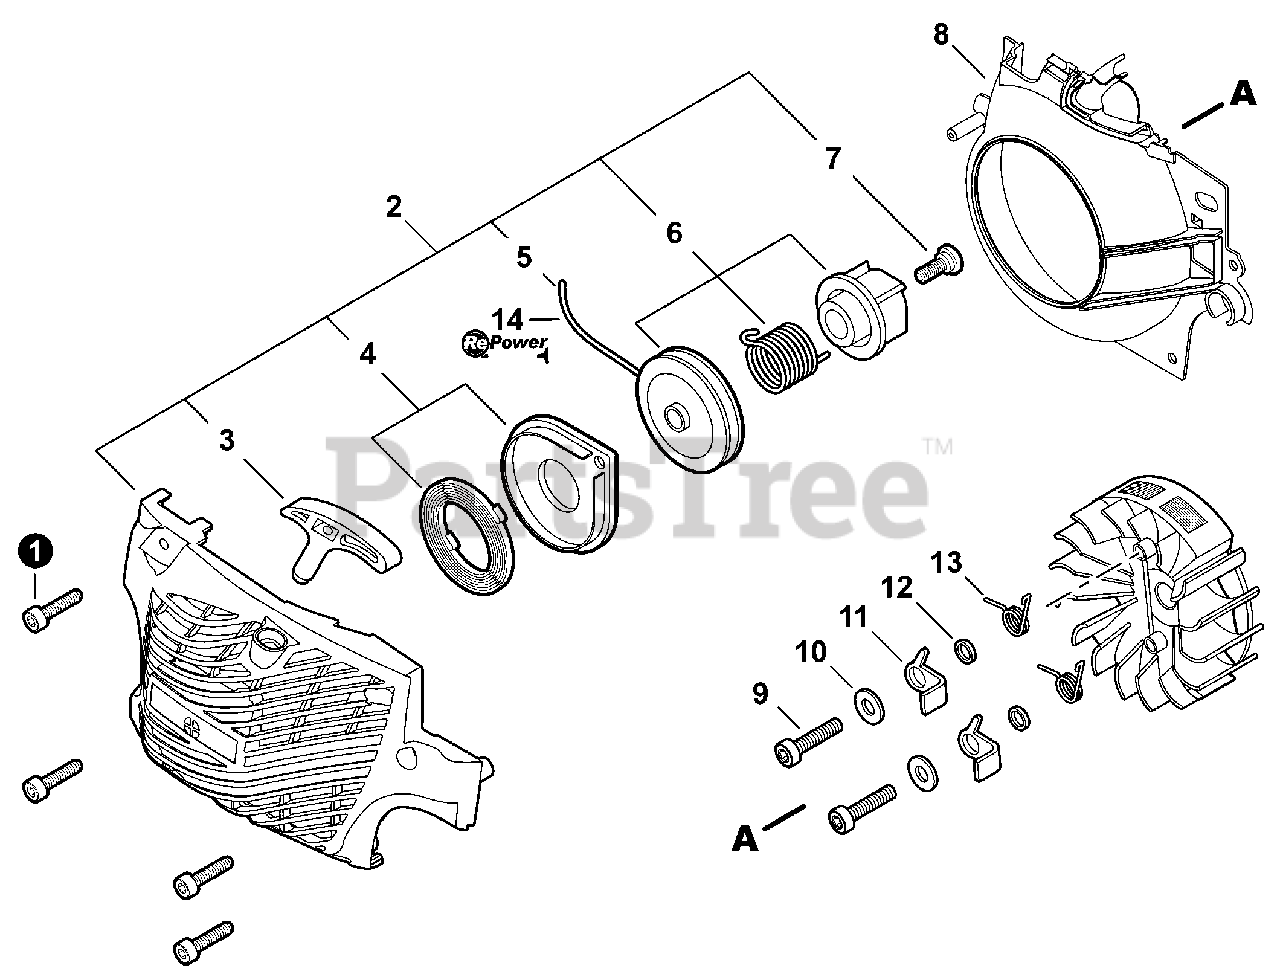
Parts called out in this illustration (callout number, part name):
1	BOLT, TORX 5×20
2	STARTER ASSY, RECOIL
3	GRIP, STARTER
4	SPRING KIT, RECOIL
5	ROPE, STARTER 3.5×900
6	REEL KIT, ROPE
7	SCREW
8	COVER, FAN
9	BOLT 5×14
10	WASHER 5.5×12×0.8
12	SPACER 5.2×8×2.1
13	SPRING, TORSION
14	BULK STARTER ROPE - Ø 3.5 MM×61 M
